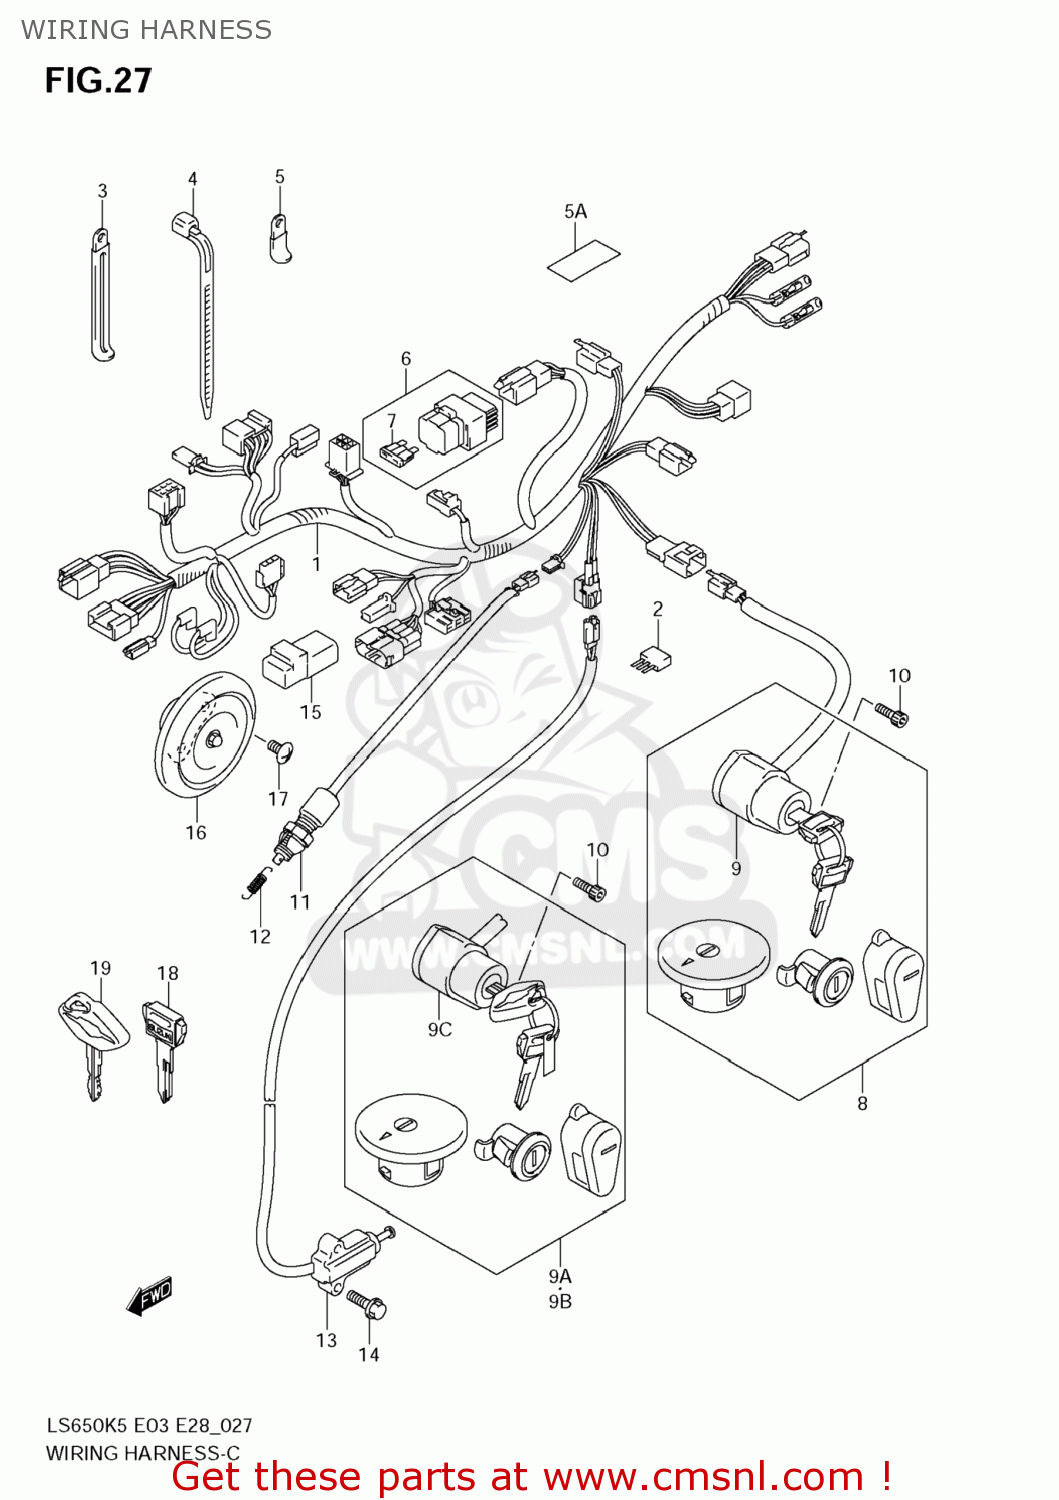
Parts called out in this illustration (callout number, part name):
1	HARNESS,WIRING
2	DIODE(STANLEY DE8804)
3	CLAMP(L:80)
4	CLAMP(L:95)
5	CLAMP,WIRING HARNESS
5A	PROTECTOR(30X30X3)
6	BOX ASSY,FUSE
7	FUSE(20A)
8	LOCK SET
9	SWITCH ASSY,IGNITION
9A	LOCK SET
9B	LOCK SET
9C	SWITCH ASSY,IGNITION
10	BOLT
11	SWITCH ASSY,STOP LAMP
12	SPRING
13	SWITCH ASSY,SIDE STAND WARNING
14	BOLT
15	RELAY ASSY
16	HORN ASSY
17	SCREW
18	KEY,BLANK(TYPE:C)
19	KEY,BLANK(TYPE:C)
